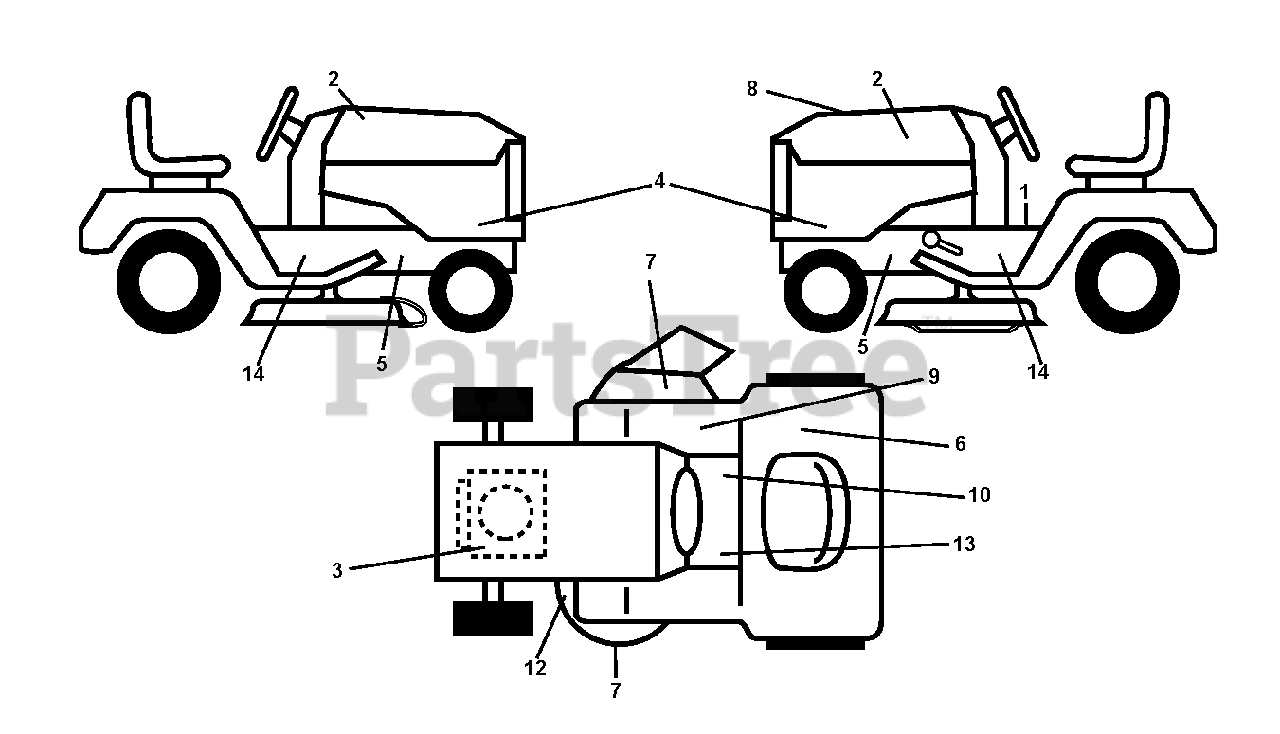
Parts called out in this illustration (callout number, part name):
1	LABEL
2	RP.DECAL.BADGE.170MM.TEXTLOGO
3	DECAL
6	Decal, Fender 100 DB/CE
7	DECAL.INTERNATIONL.CUTFINGER
9	DECAL
10	DECAL PARK BRAKE
12	DECAL DECAL V-BELT 97 CM CRD
13	DECAL
